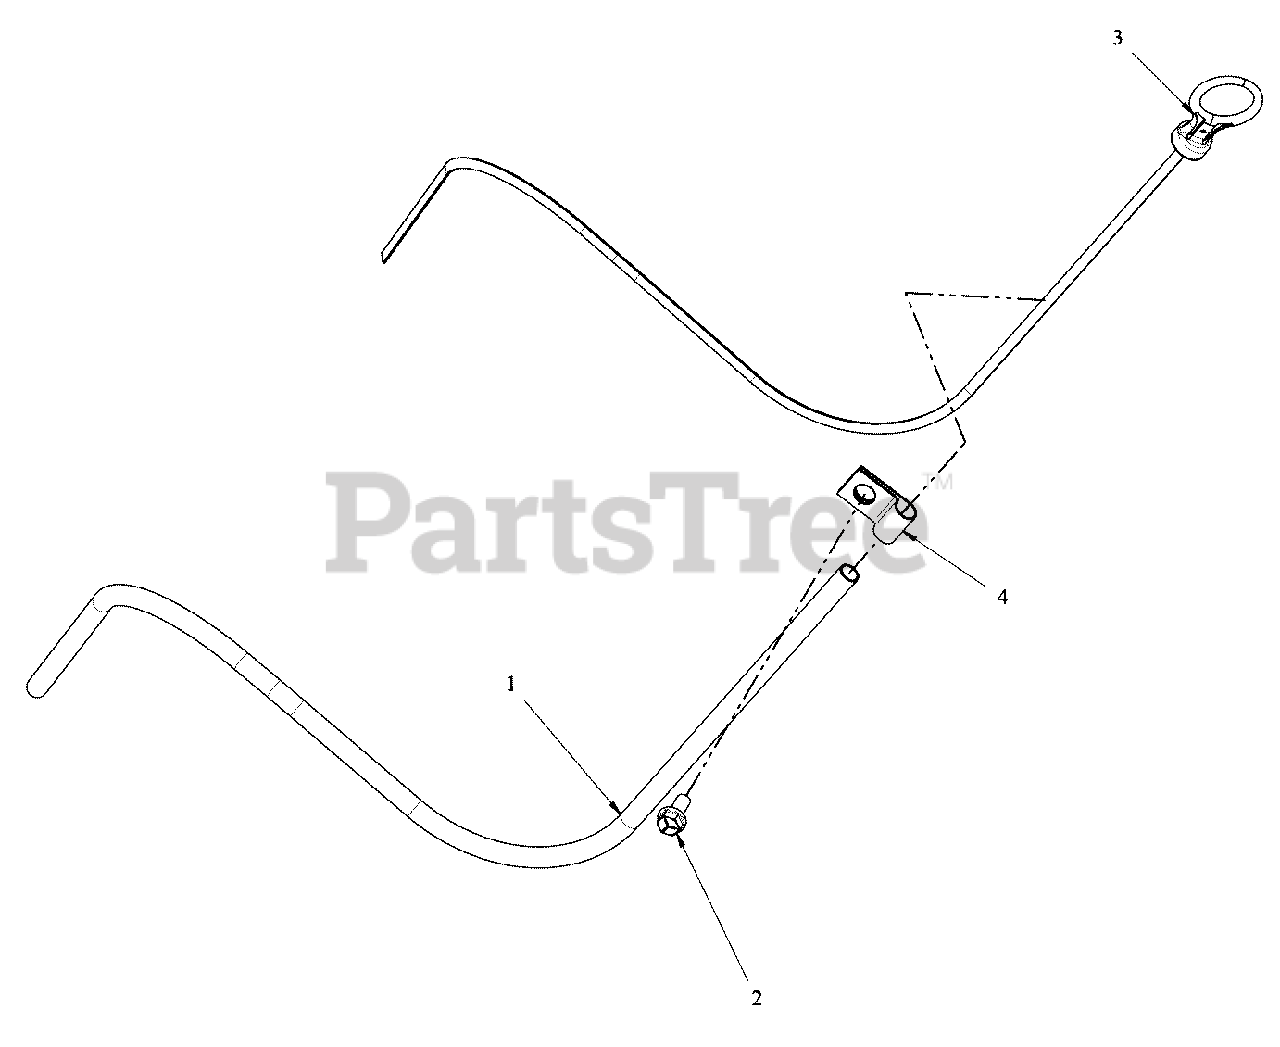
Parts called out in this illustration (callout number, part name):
1	TUBE, DIPSTICK
2	BOLT
3	DIPSTICK
4	CLAMP, D/S TUBE
